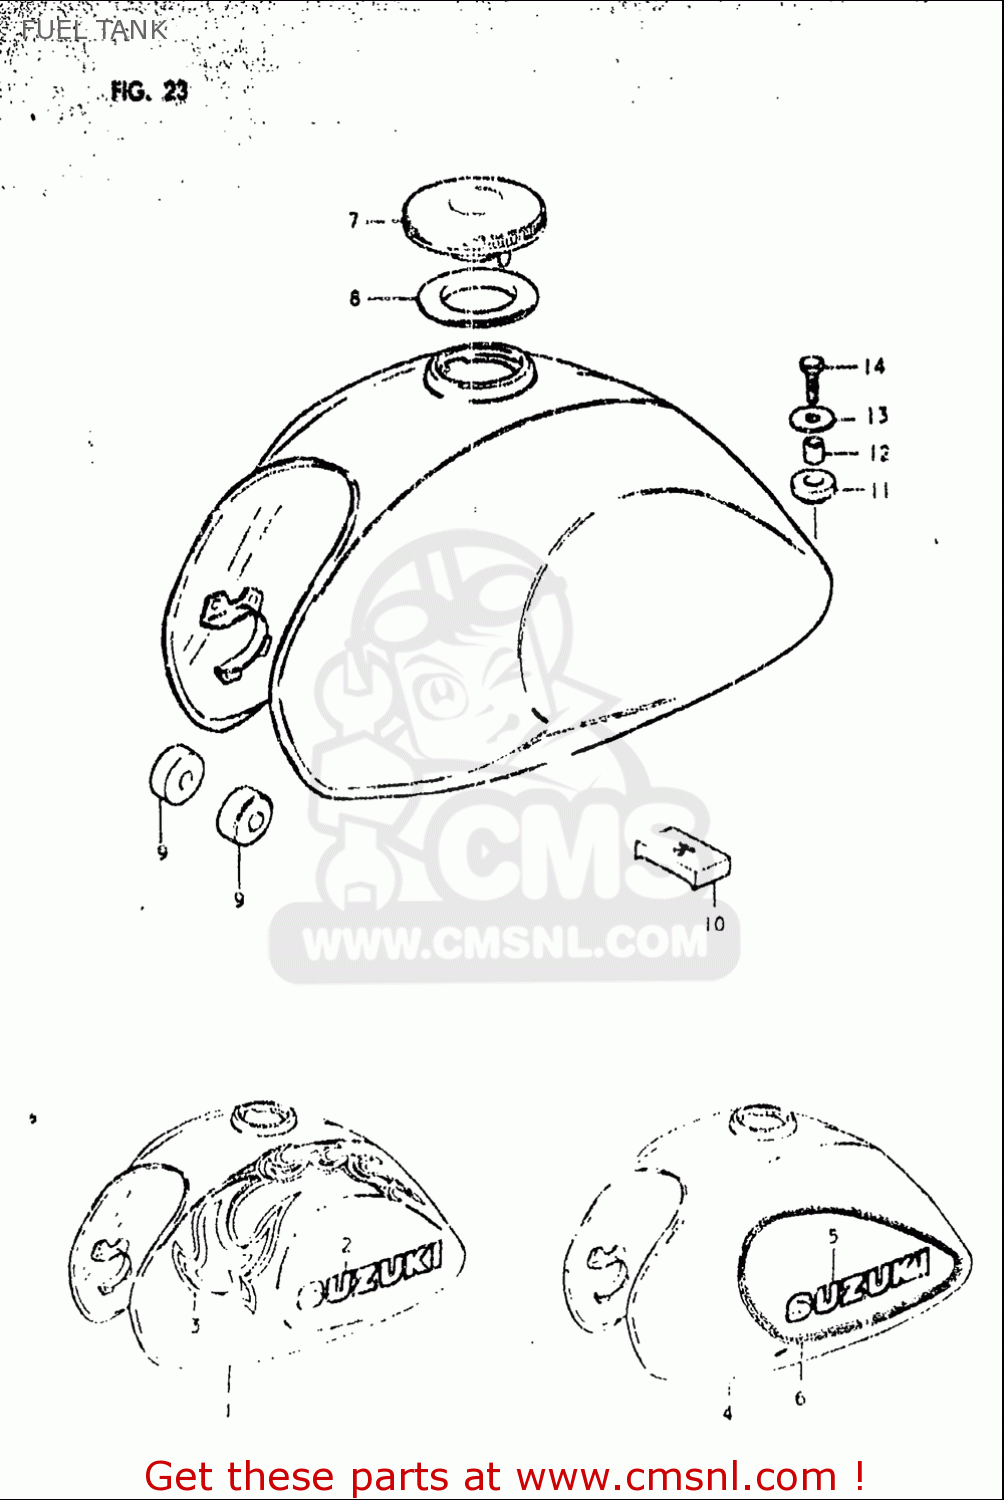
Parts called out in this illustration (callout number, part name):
5	EMBLEM(WHITE)
7	CAP ASSY,FUEL TANK FILLER
8	GASKET (NAS)
9	CUSHION
11	CUSHION
12	SPACER(6.5X10X10)
13	WASHER(6.5X24X1.6)
14	BOLT
